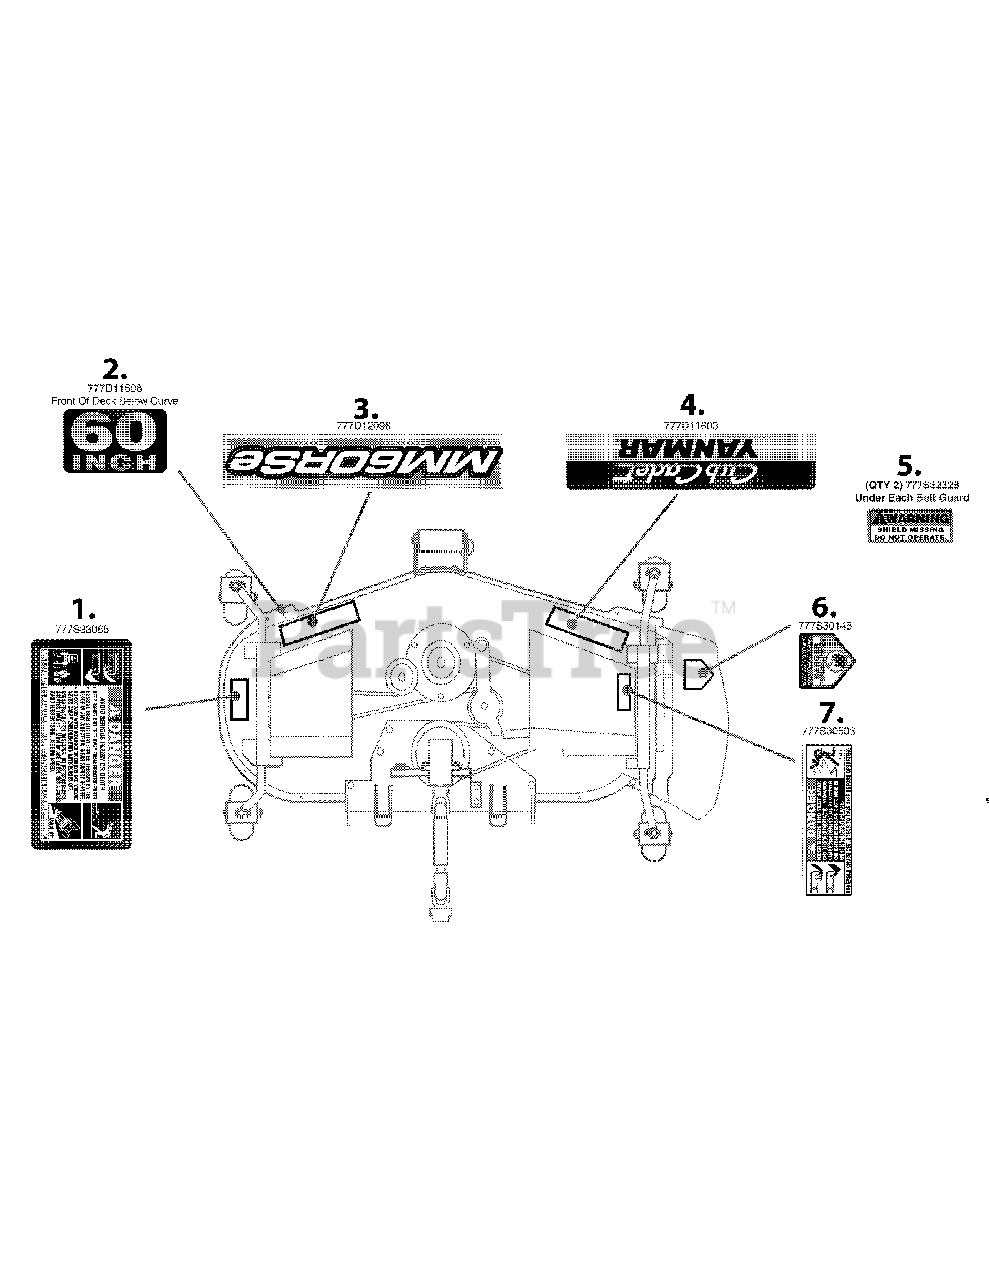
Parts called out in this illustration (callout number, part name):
1	LABEL-SFTY DNGR
2	LABEL-60 INCH
3	LABEL-MM60RSE DECK
4	LABEL-CUB YANMAR
5	DECAL-WARNING
6	LABEL
7	LABEL-DANGER CHUTE
